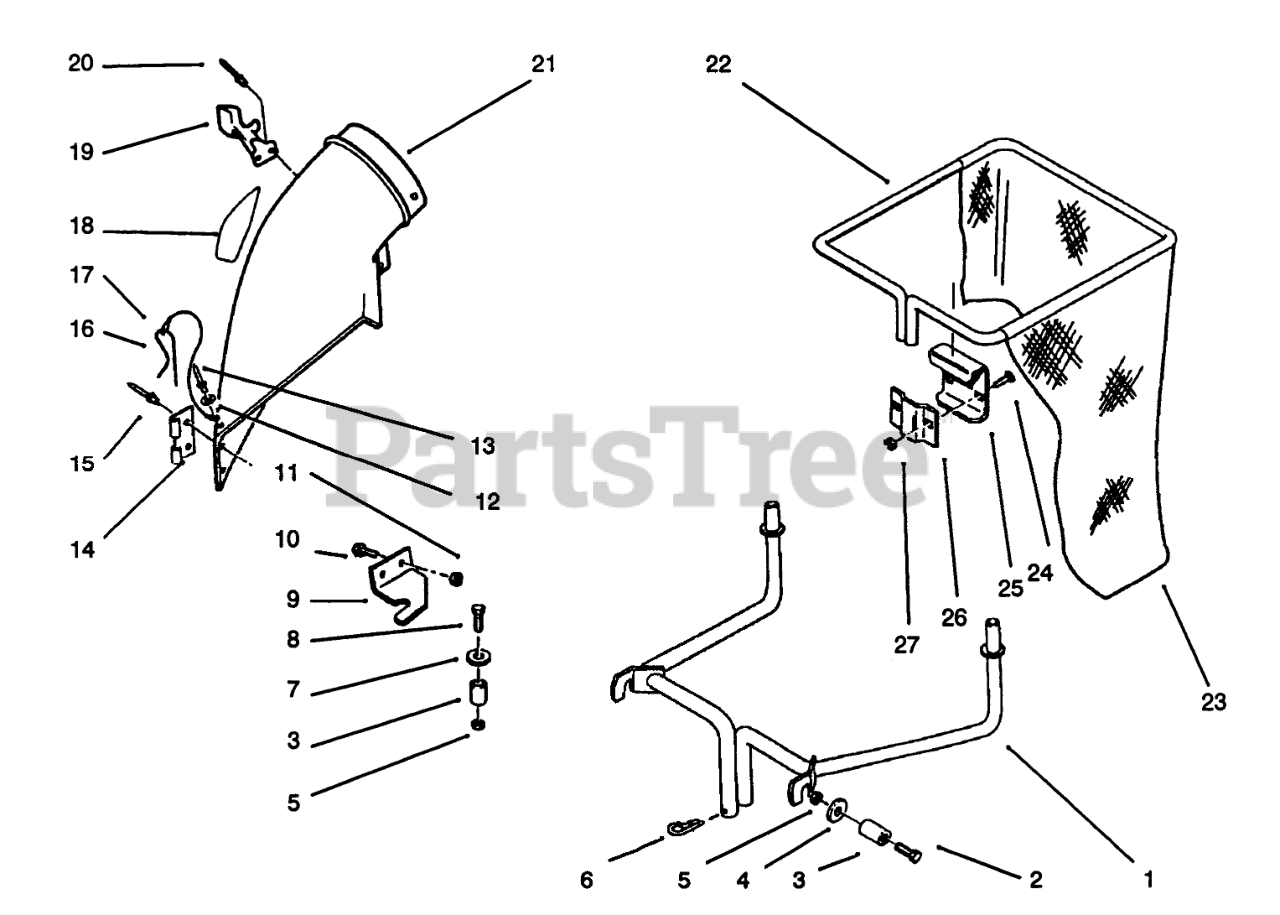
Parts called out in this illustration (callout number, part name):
1	Bracket-Quick Attach
2	SCREW-HH
3	SPACER
4	WASHER
5	NUT-LOCK, NI
6	Hairpin
7	SCREW-HH
8	SCREW-HH
9	LATCH-BAGGER ELBOW
10	Bolt
11	NUT-LOCK, NI
12	NUT-LOCK, NI
13	RIVET-BLIND
14	BRACKET-MOUNTING, CHUTE
15	RIVET-BLIND
16	PIN-LOCKING, CHUTE
17	LANYARD
18	Decal-Danger
19	Latch-38"
20	NUT-LOCK, NI
21	Chute Assembly (Incl. Ref. #14-20)
22	Bag Frame
23	Bag
24	BOLT-CARR
25	Bag Hanger
26	Clamp
27	NUT-LOCK, NI
